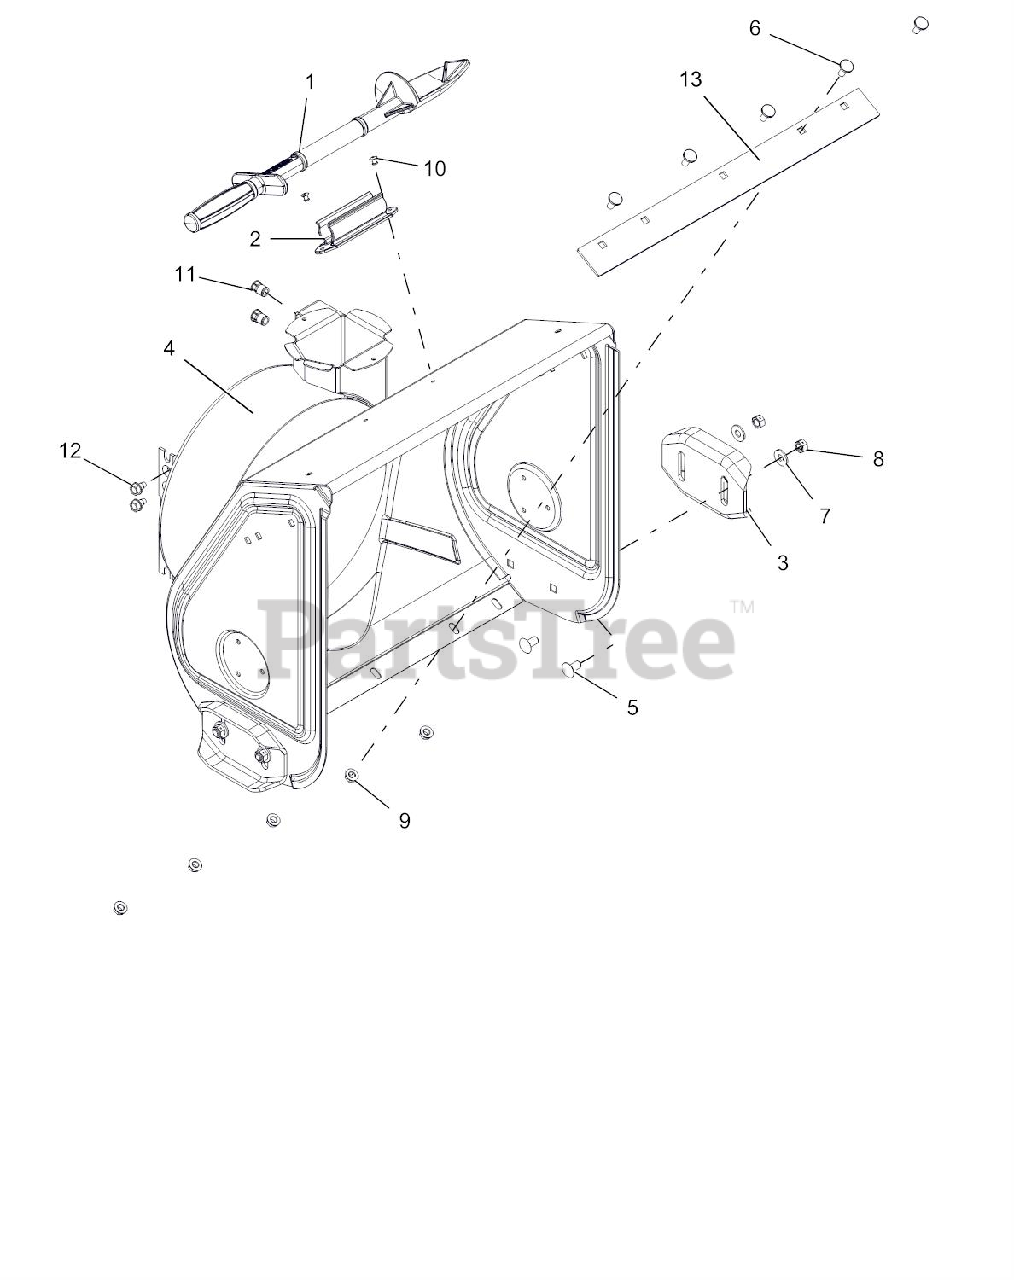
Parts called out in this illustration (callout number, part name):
1	DEVICE, SNOW CLEAN OUT
2	MOUNT, SNOW CLEAN OUT
3	SKID SHOE, REVERSIBLE - ORANGE
4	BLOWER HOUSING, 20" HB SERVICE
5	@BLT-RHDSSQNK .38-16X.75 G5YZ
6	BOLT, MODIFIED HEAD CARRIAGE
7	@WSHR-FL-STL.38X.875X.083 YWZC
8	@NUT-LK-CTR .38-16 YWZC
9	@NUT-LK-TOP-FLG .31-18 YWZC
10	RVT-POP .187 YZ
11	NUT, THREADED INSERT .38-16
12	@SCR-TAP .31-18X.50 HWH TR YWZ
13	SCRAPER BLADE, 20"
